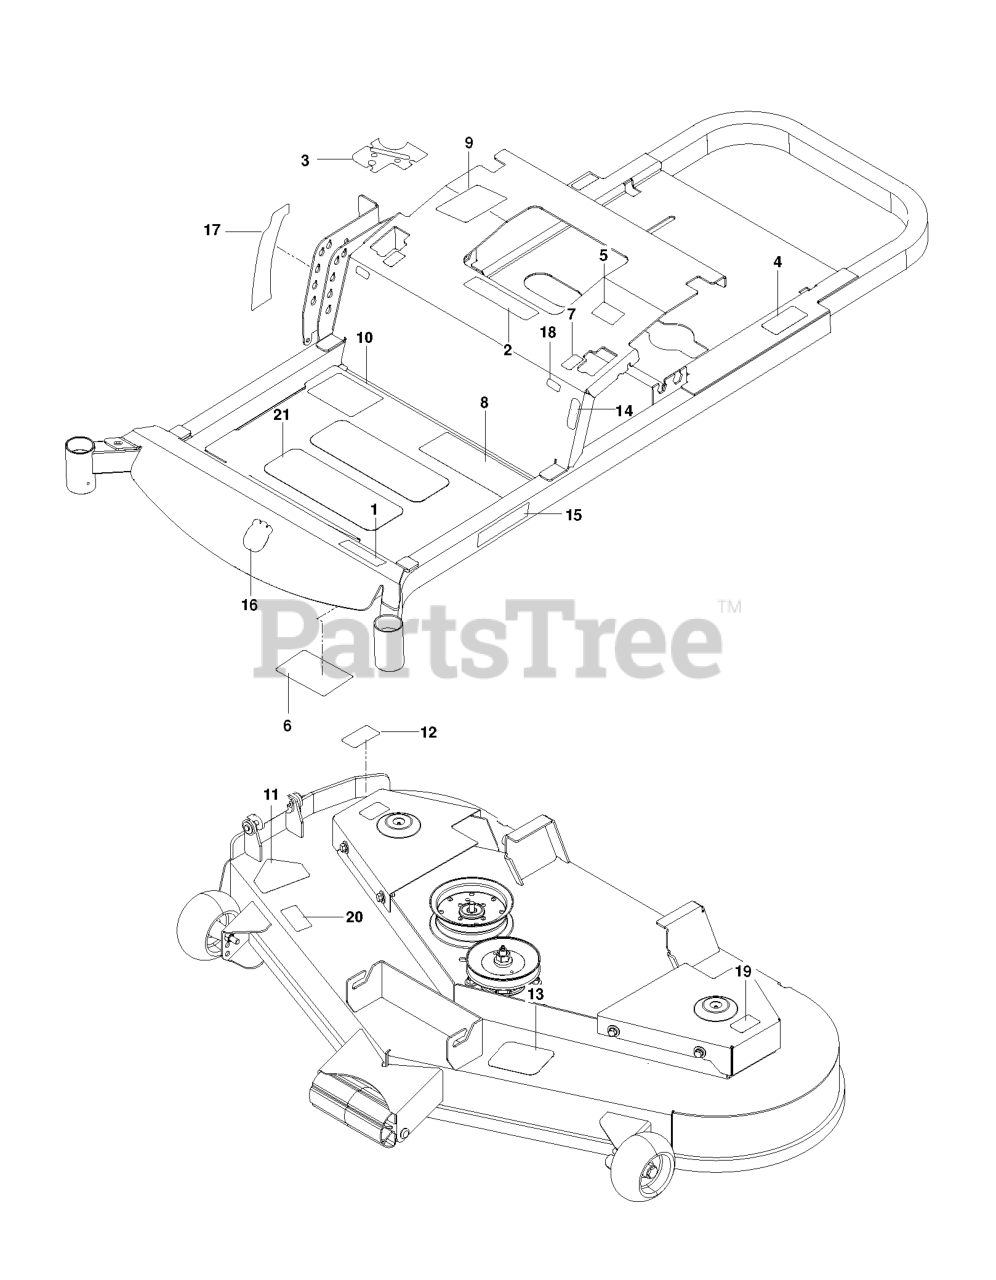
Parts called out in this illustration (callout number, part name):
1	DECAL RZ4824F
2	EURO DECAL-BATTERY WARNIN6
3	DECAL, CTRL PANEL, HUSQ
4	DECAL, DO NOT TOW
5	DECAL, EXITING MOWER
6	DECAL, SERVICE
7	DECAL, MOTION CONTROL
8	DECAL, SAFETY WARNING
9	DECAL, CUSTOMER RESPNSIBILITY
10	DECAL.ZTR.STRTNGINST.REMOTECHK
11	DECAL, DECK DEFLECTOR, WARNING
12	DECAL.DECK.6MIL./DEF.SHLD.WARN
13	DECAL, BELT ROUTING
14	DECAL, PARK BRAKE
15	RP.DECAL.BADGE.170MM.TEXTLOGO
16	DECAL.AUGER.HUSQ.CROWN.SNOW
17	DECAL, DECK HEIGHT, HUSQ
18	DECAL, F.S.T.
19	DECAL.DECK.6MIL.EURO.NOSTEP
20	DECAL, EURO SEVERING
21	ANTI-SKID PAD
